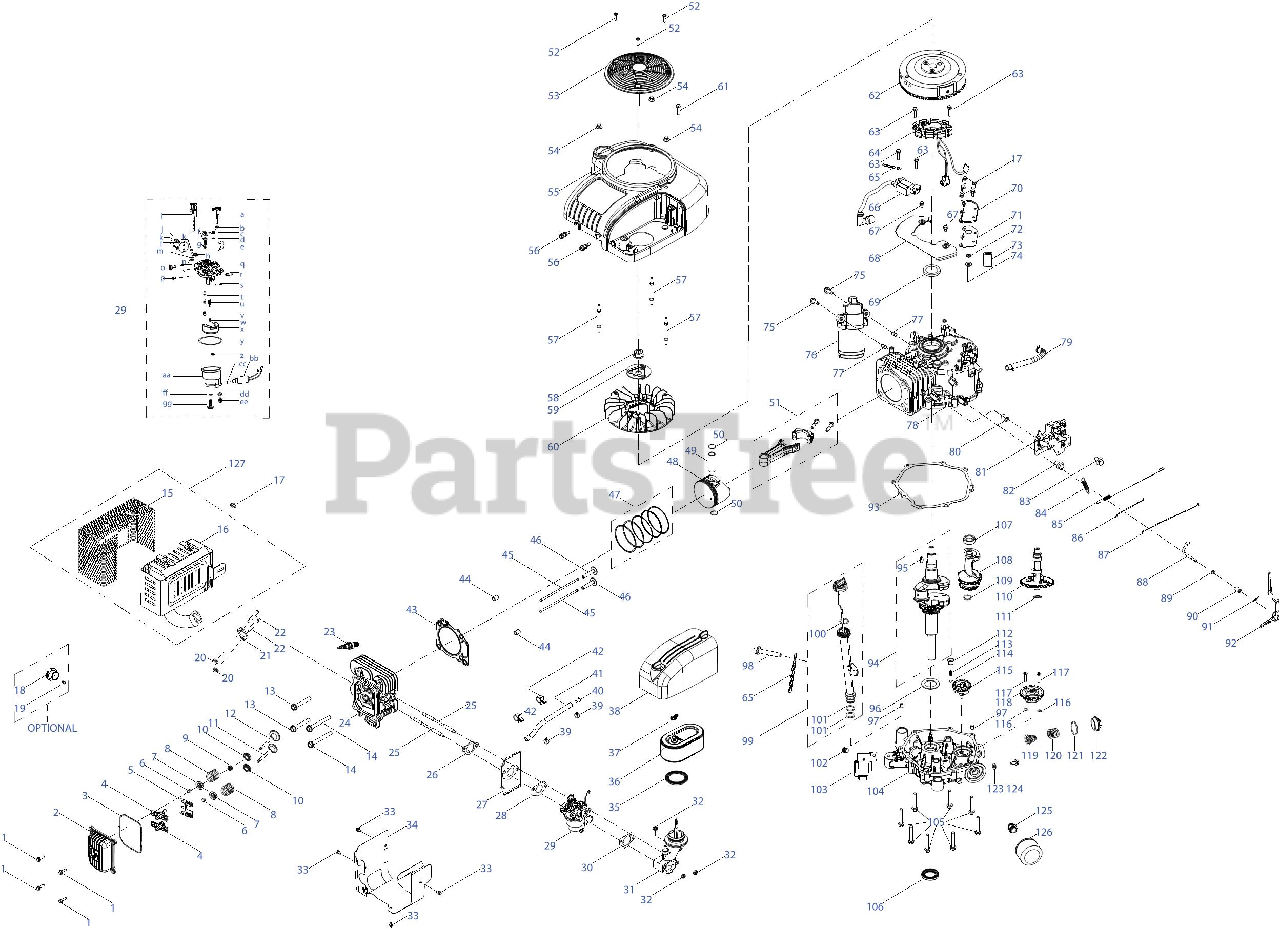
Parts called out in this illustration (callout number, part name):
1	Bolt, M6x22
2	Valve Cover
3	Gasket, Valve Cover
4	Rocker Arm Assembly
5	Rocker Arm Base
6	Valve Adjust Cap, Exhaust
7	Valve Spring Seat
8	Valve Spring
9	Intake Valve Seal
10	Valve Spring Seat
11	Exhaust Valve
12	Intake Vavle
13	Bolt, M10x1.25x65
14	Bolt, M10x1.25x85
15	Muffler Guard
16	Muffler
17	Bolt, M6x14
18	Spark Arrester
19	Self-tappling Screw, ST5x8
20	Nut, M8
21	Gasket, Muffler
22	Stud, M8x47
23	Spark Plug
24	Cylinder Head
25	Stud, M6-8x140
26	Gasket, Carburetor Insulator
27	Insulator
28	Gasket, Carburetor
29	Carburetor
30	Gasket, Intake Manifold
31	Intake Manifold
32	Nut, M6
33	Bolt, M5x10
34	Shroud
35	Ring,Air Filter
36	Air Filter
36	Genuine Factory Parts AIR FILTER
37	Butterfly Nut
38	Air Filter Cover
39	Clamp
41	Fuel Hose, 6.3x 12.5x290
42	Clip
43	Gasket, Cylinder Head
44	Pin, 12x16
45	Push Rod
46	Tappet
47	Piston Ring Set
48	Piston
49	Piston Pin
50	Circlip
51	Connecting Rod Assembly
52	Self-tappling Screw, ST5.5x25
53	Shroud
54	Nut,M6
57	Stud, M6x99
58	Nut, M16x1.5
59	Cooling Fan Plate
60	Cooling Fan
61	Bolt, M6x16
62	Flywheel
63	Bolt, M6x28
64	Charging Coil
65	FLEXIBLE CLAMP
66	Ignition Module
67	Bolt, M6x10
68	Shield
69	Oil Seal, 35x 52x7
70	Breather Cover
71	Gasket, Breather Cover
72	Breather Valve
73	Breather Filter Screen
74	Second Air Valve Seat
75	Bolt, M8x40
76	Electric Starter
77	Pin, 10x14
78	Crankcase
79	Breather Hose
80	Bush, 6.5x 15x20
81	Governor Gear Bracket Assembly
82	Bolt, M6x38
83	Bolt, M6x18
84	Governor Spring
85	Idle Spring
86	Choke Lever
87	Throttle Linkage
88	Governor Gear Shaft
89	Washer, 6x1x 12
90	GOVERNOR SEAL
91	Cotter Pin
92	Governor Lever
93	Gasket, Crankcase
94	Crankshaft
95	Woodruff Key
96	Washer, 35.4x2x 54
97	Pin, 8x14
98	Bolt, M6x35
99	Dipstick
99	Oil Fill Tube
100	O-Ring, 21.9x2.62
101	O-Ring, 21.2x2.8
102	ENGINE PLUG 3/8 NPT
103	Regulator
104	Crankcase Cover
105	Bolt, M8x54
106	Oil Seal, 35x 52x7
107	Bearing, 6202
108	Balance Shaft
109	Washer, 15.4x1x 25
110	Camshaft
111	Washer, 16.4x1x 24
113	Spring
114	Ball S 6.35
115	Governor Gear
116	O-Ring, 10x2.65
118	Oil Pump
119	Breather Filter Screen
120	Breather Spring
121	O-Ring, 35.5x2.65
122	Breather Cover
123	Washer, 8.3x1.5x 17
124	Bolt, M8x15
125	Connection Pipe
126	Oil Filter
126	Cub Cadet OIL FILTER
126	Genuine Factory Parts OIL FILTER
127	Muffler
